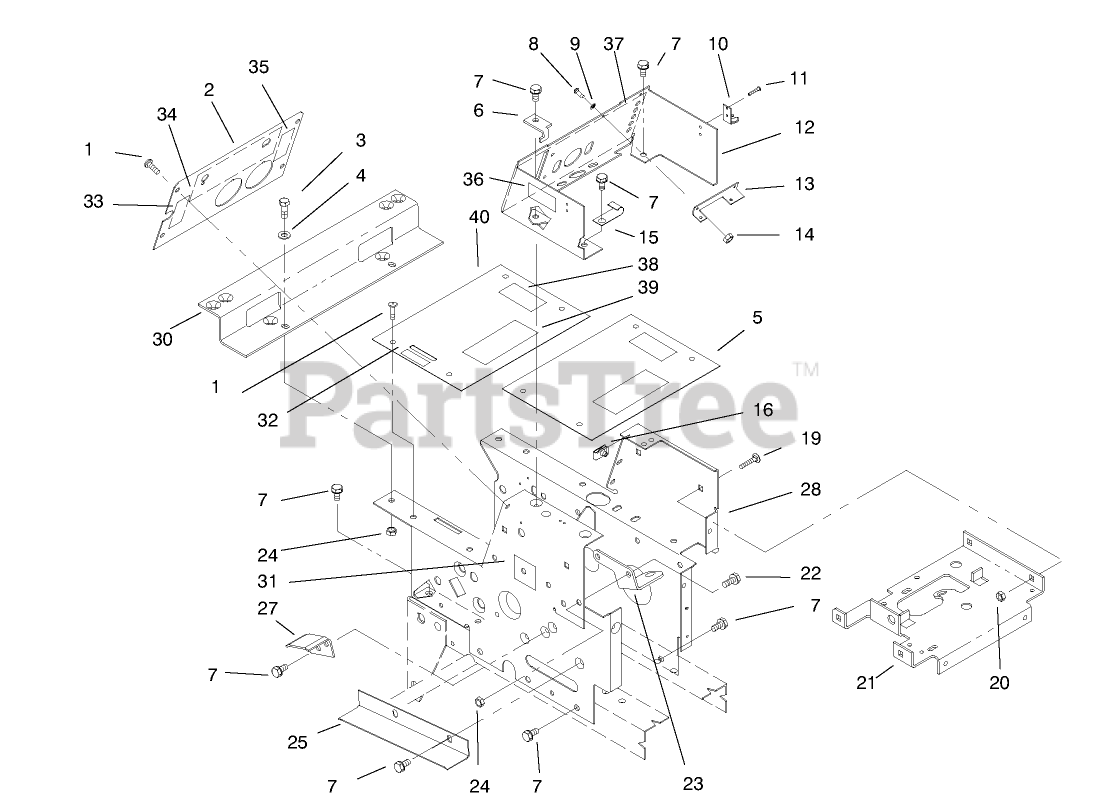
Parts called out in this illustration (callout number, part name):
1	SCREW-PPH
2	PLATE-HOODSTAND
3	SCREW-HH
4	WASHER-PLAIN
6	STOP-PTO
8	SCREW-PAN
9	Washer-Lock
10	KEEPER-LATCH
11	RIVET-POP
12	Console
13	BRACKET
15	J-CLIP
21	Bracket-Battery Support
22	SCREW-HH
24	NUT-LOCK, NI
25	Angle-Belt Guard
27	Bracket-Belt
28	Hoodstand
30	Bracket-Fender
31	DECAL - MODEL 314-H
32	DECAL-COLD START
33	DECAL PTO CLUTCH
34	DECAL-BACK PLATE
35	DECAL-CHOKE
38	DECAL-PARKING BRAKE
39	DECAL-DANGER
40	PLATE SHIFT
